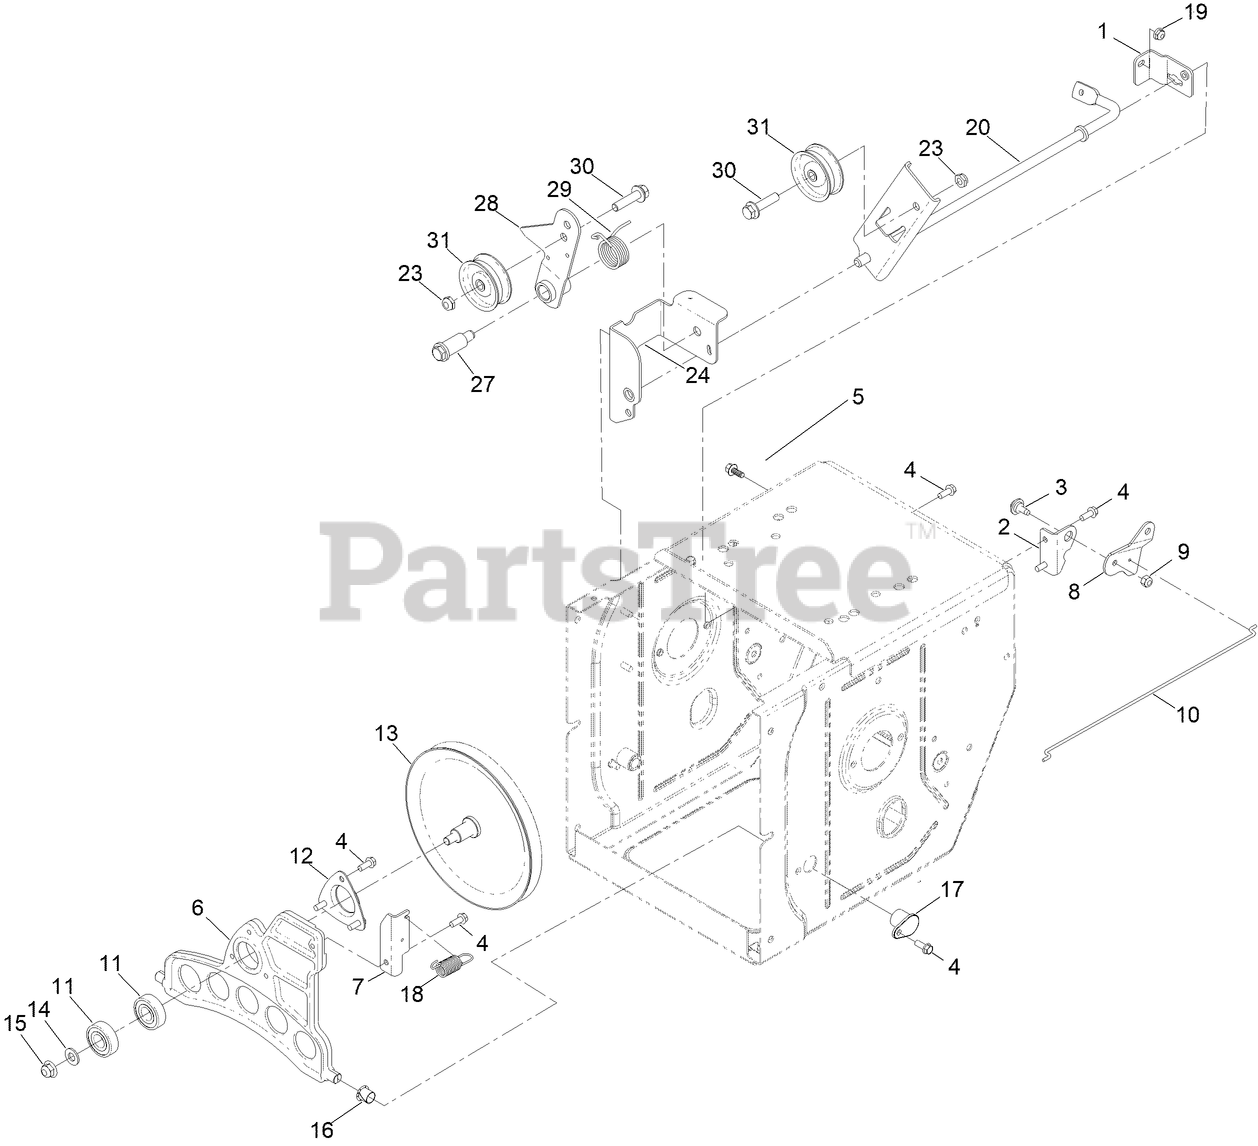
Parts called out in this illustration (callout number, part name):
1	BRACKET-CLUTCH, IMPELLER
2	BRACKET- BELLCRANK
3	SCREW-SHOULDER
4	SCREW-HWH
5	SCREW-HHF
6	PLATE-FRICTION, WHEEL
7	BKT-TRACTION PLATE
8	BELLCRANK-DRIVE
9	NUT-HEX
10	LINK-DRIVE
11	BEARING-BALL
12	RETAINER-BEARING
13	PULLEY-TRACTION
14	WASHER-FLAT
15	NUT-HF, NI
16	BUSHING-NYLINER
17	BUSHING-PLATE, TRACTION
18	SPRING-EXTENSION
19	NUT-HF
20	ARM-CLUTCH, IMPELLER
23	NUT-HEX
24	BRACKET-BRAKE, CLUTCH
27	BOLT-SHOULDER
28	ARM-IDLER, TRACTION
29	SPRING-TORSION
30	SCREW-HHF
31	PULLEY-IDLER
